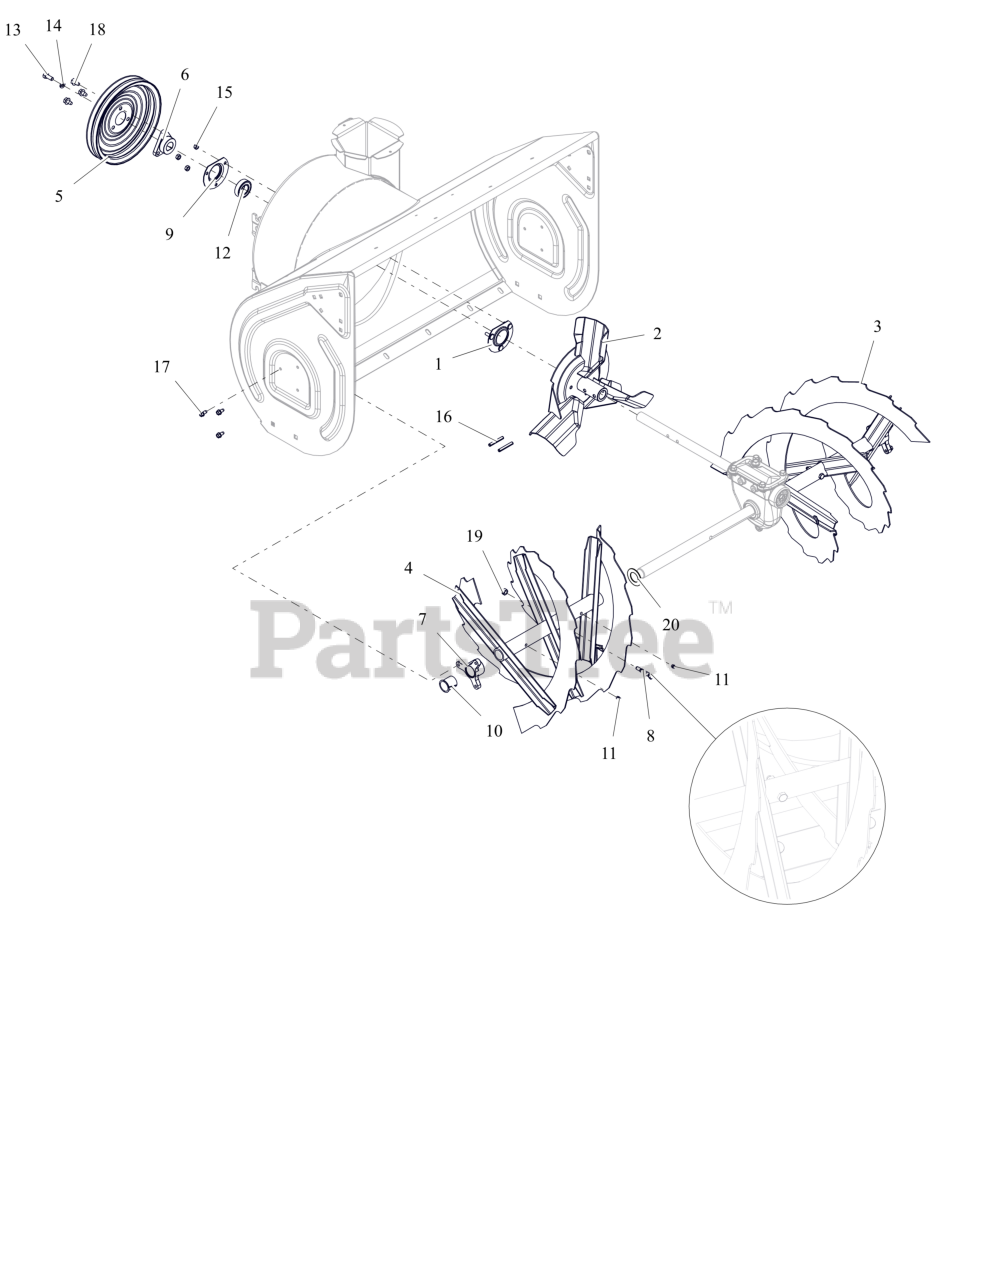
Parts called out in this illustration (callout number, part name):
1	BEARING FLANGE
2	IMPELLER, 3 BLADE-14"
3	RAKE, LH-32"(1 ID X 15.75 OD)
4	RAKE, RH-32"(1 ID X 15.75 OD)
5	PULLEY, SPIN FORM DUAL GROOVE
6	PULLEY HUB, D-BORE .87 PRO
7	BUSHING, RAKE SHAFT 1"
8	SHEAR BOLT SERVICE ASSEMBLY (INCLUDES NUT)
9	BEARING FLANGE
10	BSHG-FLG SPLIT NYLINER 1.0" HP
11	ZERK,FITTING .25X.125 DRIVE IN
12	BRG-BALL .876X1.75X.50 RSTFP
13	BLT, HEX .31-24X.750 G5 ZCC
14	WSHR, LK-HVY .312X.097 ZCC
15	NUT,LK-CTR .25-20 GA ZCC
16	PIN-ROLL .250X1.75
17	SCR-TAP .25-20X.50 HWH ZCC
18	SCR,TAP .312-18X.50 HWH TR ZCC
19	NUT,LK-CTR .31-18 GA ZCC
20	WSHR- FLT 1.010X1.755X.062 ZCC
